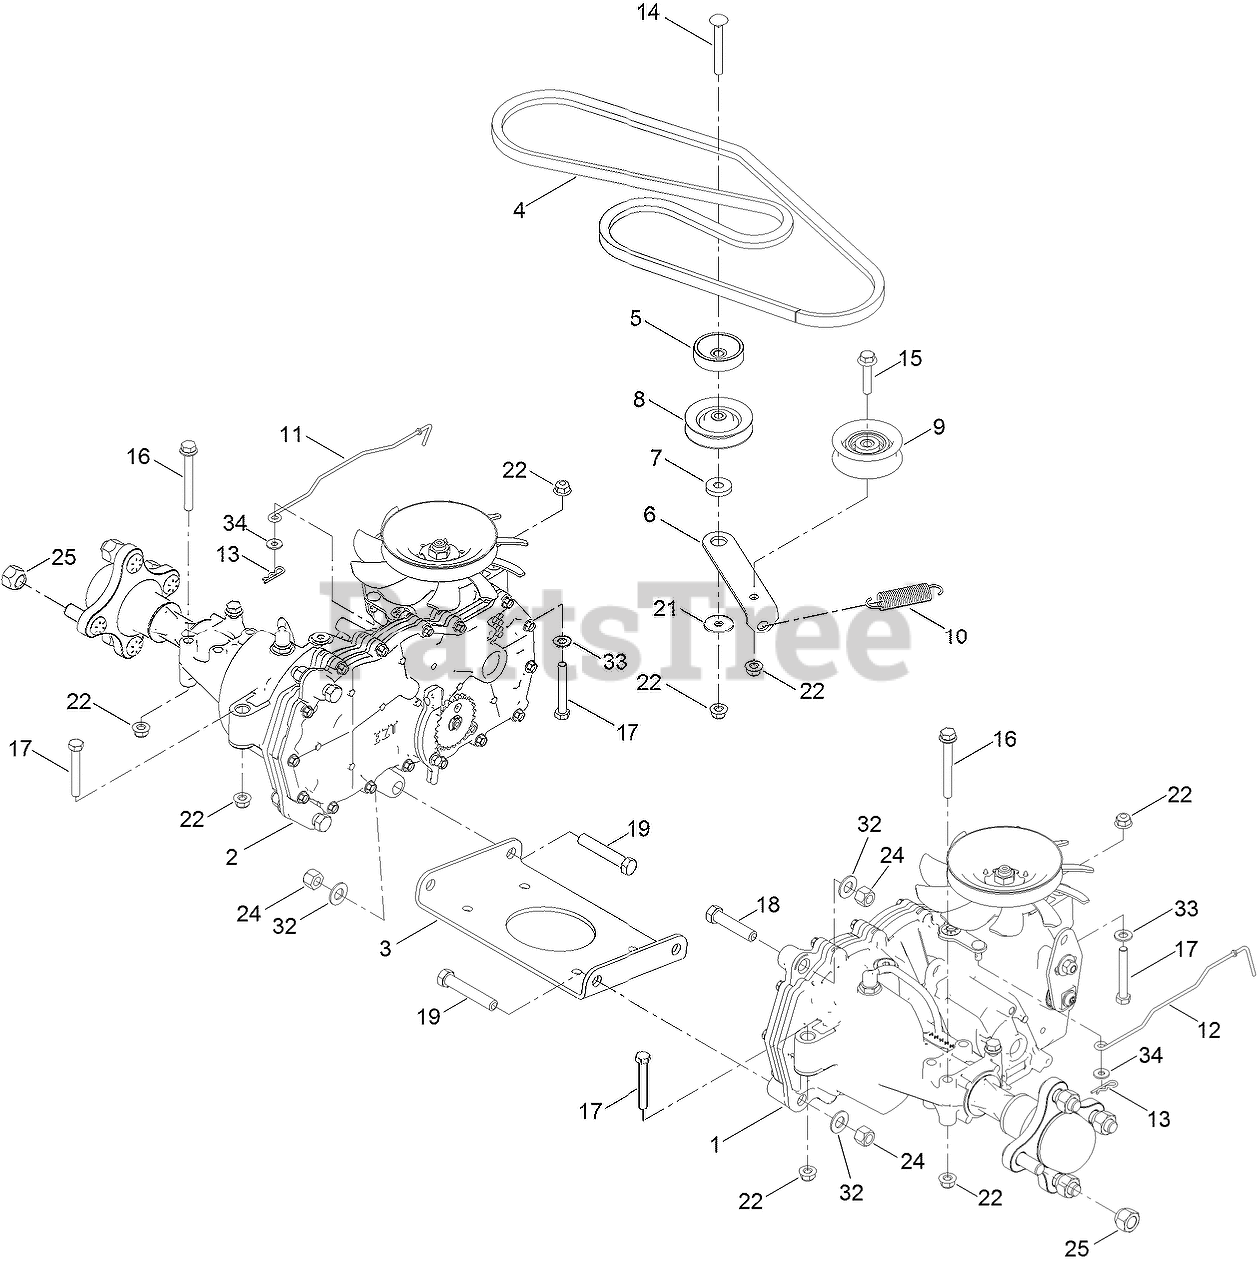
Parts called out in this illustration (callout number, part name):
1	LH HYDRO TRANSAXLE ASM
2	RH HYDRO TRANSAXLE ASM
3	CROSSPLATE-HYDRO
4	V-BELT
5	SPACER
6	ARM-IDLER
7	SPACER-IDLER ARM
9	PULLEY-IDLER, FLAT
10	SPRING-PEDAL, RETURN
11	ROD-BYPASS, RH
12	ROD-BYPASS, LH
13	PIN-HAIR
14	SCREW-CARR
15	SCREW-HHF
16	SCREW-HHF
17	SCREW-HH
18	SCREW-HH
19	SCREW-HH
21	WASHER-PIVOT
22	NUT-HF
24	NUT-HEX, NI
25	NUT-LUG
32	WASHER-FLAT
33	WASHER-PLAIN
34	WASHER
